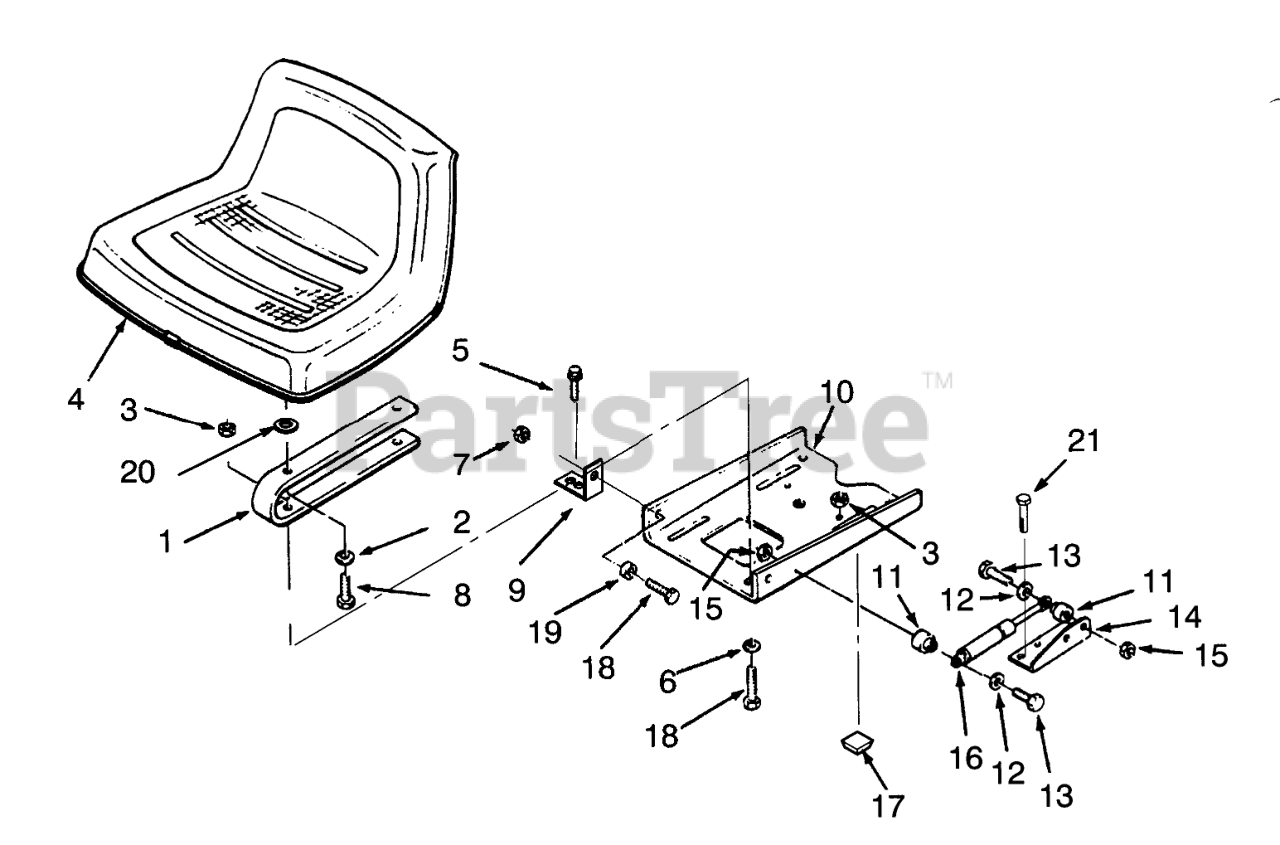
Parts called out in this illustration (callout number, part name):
1	Seat Spring
2	WASHER-LOCK
3	NUT-LOCK, NI
4	SEAT V-410
5	BOLT HEX 5/16-18X7/8
6	WASHER-PLAIN
7	NUT-LOCK, NI
8	SCREW-HH
9	BRACKET-PIVOT
10	Plate-SeatPivot
11	SPACER
12	WASHER-FLAT
13	SCREW-HH
14	BRACKET-CYLINDER R
15	NUT-LOCK, NI
16	GAS SPRING
17	BUMPER SJ5514 BLACK
18	SCREW-HH
19	BUSHING
20	SPACER-NYLON
21	Bolt
